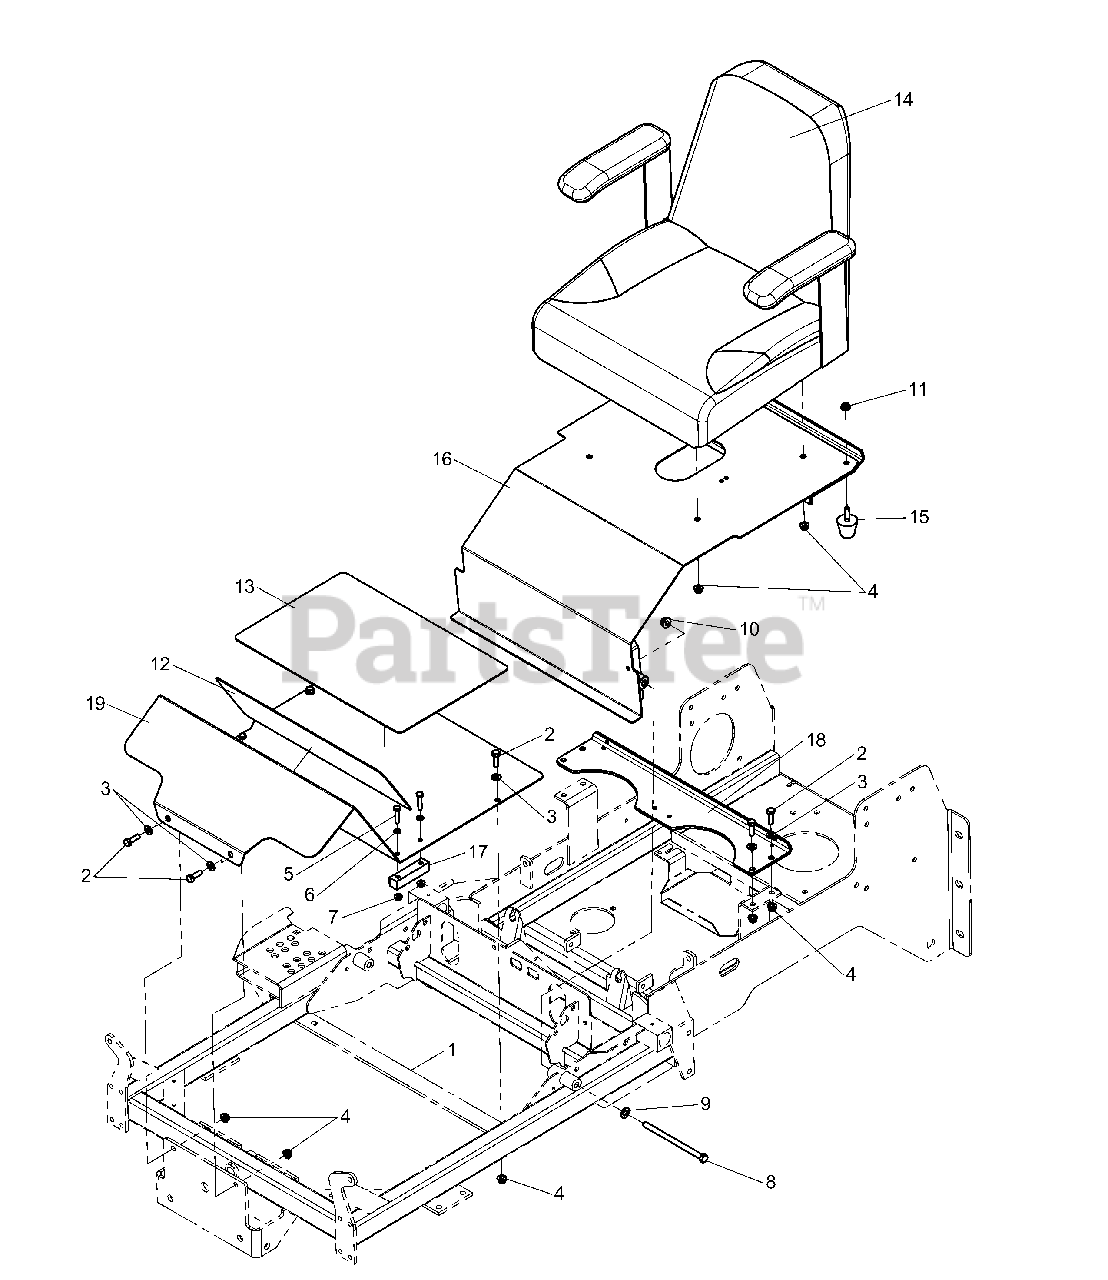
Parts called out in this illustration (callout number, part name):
1	MAIN FRAME (See Main Frame Group)
2	BOLT, 5/16-18 X 1
3	WASHER 5/16" SAE
4	NUT, 5/16-18 Hex Nylock Flange
5	BOLT, 1/4-20 X 1-1/4
6	WASHER, 1/4 SAE (5025154)
7	NUT, 1/4-20 HEX NYLOCK FLANGE (5025391)
8	BOLT, 3/8-16 X 6
9	WASHER 3/8" SAE
10	NUT, 3/8-16 Hex Nylock Flange
11	NUT, 5/16-18 Hex Small Serrated Flange
12	SAFETY WALK, FLOOR REST
13	SAFETY WALK, FLOOR PLATE
14	SEAT, BLACK
15	BUMPER, RUBBER 5/16-18
16	ASSM, SEAT PLATE (Includes safety decal) (Early Models)
16	ASSM, SEAT PLATE (Includes safety decal) (Later Models with ROPS)
17	BLOCK, DECK LIFT SUPPORT
18	SUPPORT, SEAT PLATE (Early Models)
18	SUPPORT, SEAT PLATE (Later Models with ROPS)
19	PLATE, FLOOR
